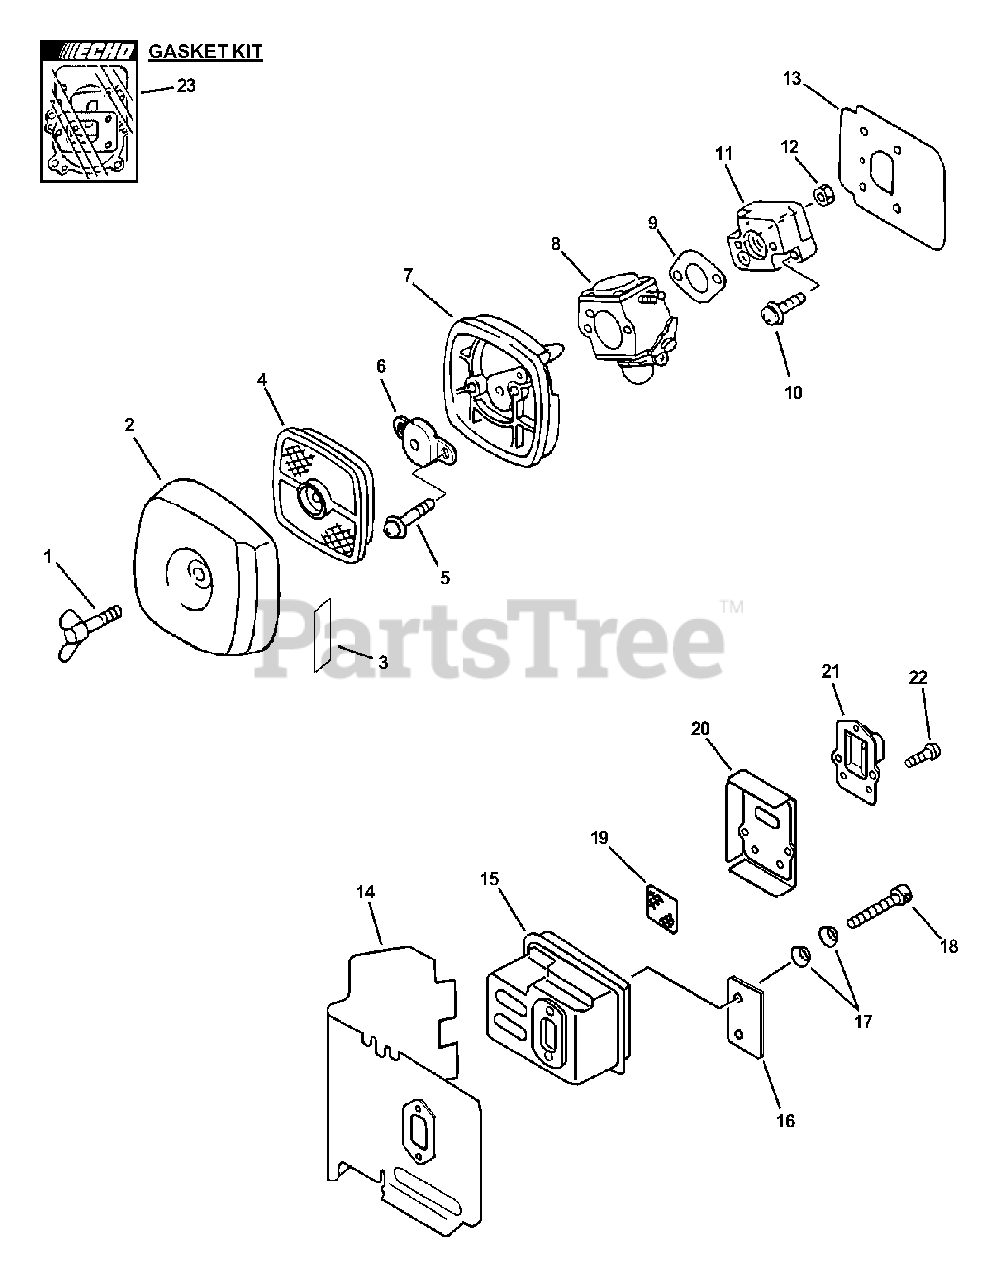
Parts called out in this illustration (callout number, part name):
1	BOLT, WING 5×20
2	COVER, AIR FILTER - GRAY
3	LABEL, CHOKE
4	FILTER, AIR - SINGLE LAYER
5	SCREW 5×65
6	PLATE, PREVENT
7	CASE, AIR FILTER - GRAY
8	CARBURETOR - C1U-K58
9	GASKET, INTAKE
10	SCREW 5×20
11	INSULATOR, INTAKE
12	NUT M5
13	HEAT SHIELD, INTAKE
14	SHIELD, EXHAUST
15	MUFFLER
16	PLATE, EYE
17	CONICAL WASHER
18	BOLT 5×55
19	SCREEN, SPARK ARRESTER
20	GASKET, EXHAUST
21	GUIDE, EXHAUST
22	SCREW 4×10
23	GASKET KIT
